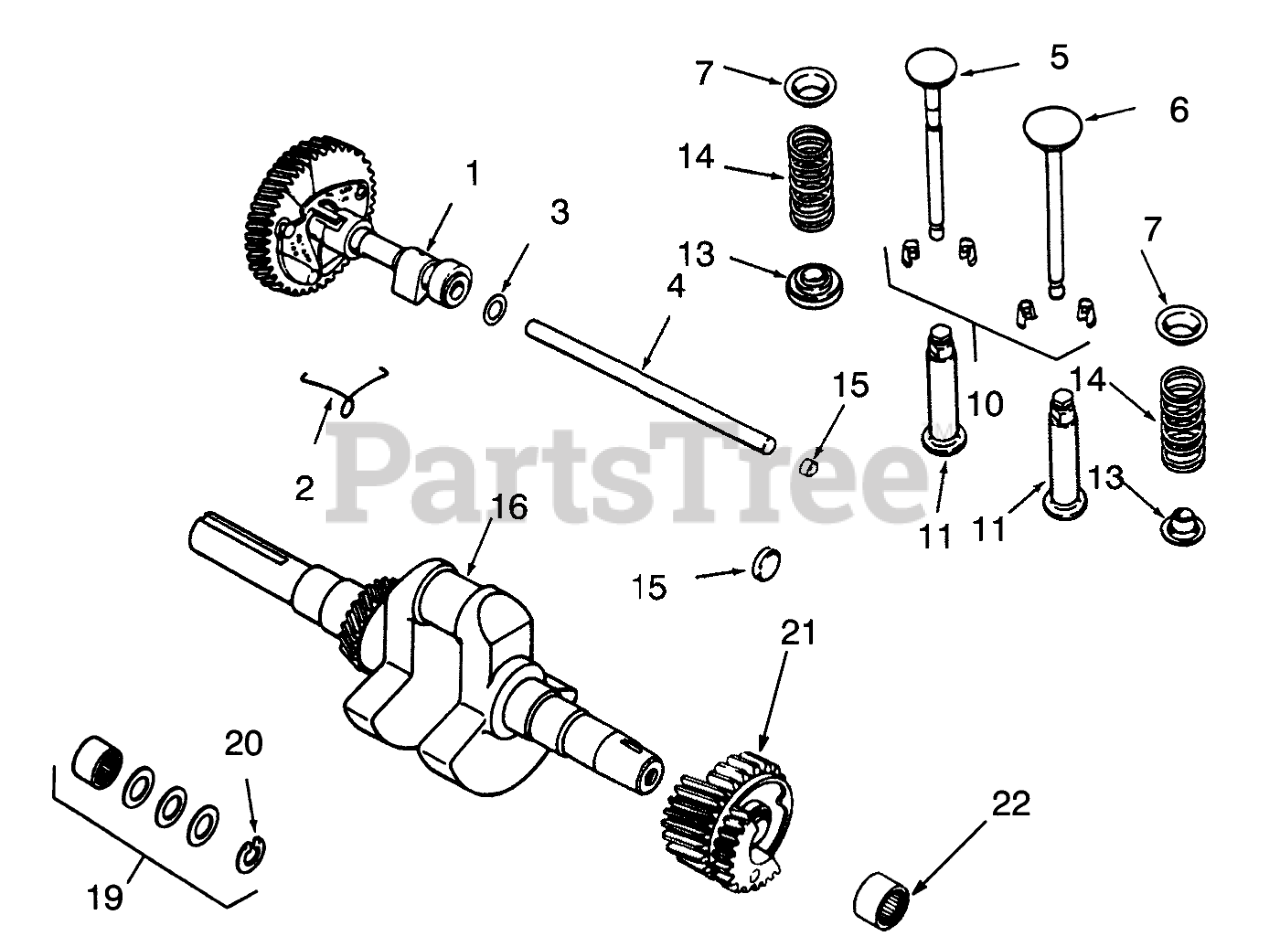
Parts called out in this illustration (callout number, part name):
1	Camshaft Assy (Incl. Ref. #2)
2	Spring
3	Spacer .005
4	Camshaft Pin
5	Valve-Exhaust
6	Valve-Intake
7	UpperSpring Retainer
10	Kit-Retainer
11	Tappet
13	Rotator-Valve
14	Spring
16	Kit-Crankshaft (Includes Flywheel Hdwr.)
19	Kit-Spacer (Incl. Ref. #20)
20	Retainer
21	Gear Assembly (Incl. Ref. #22)
22	Bearing-Needle
